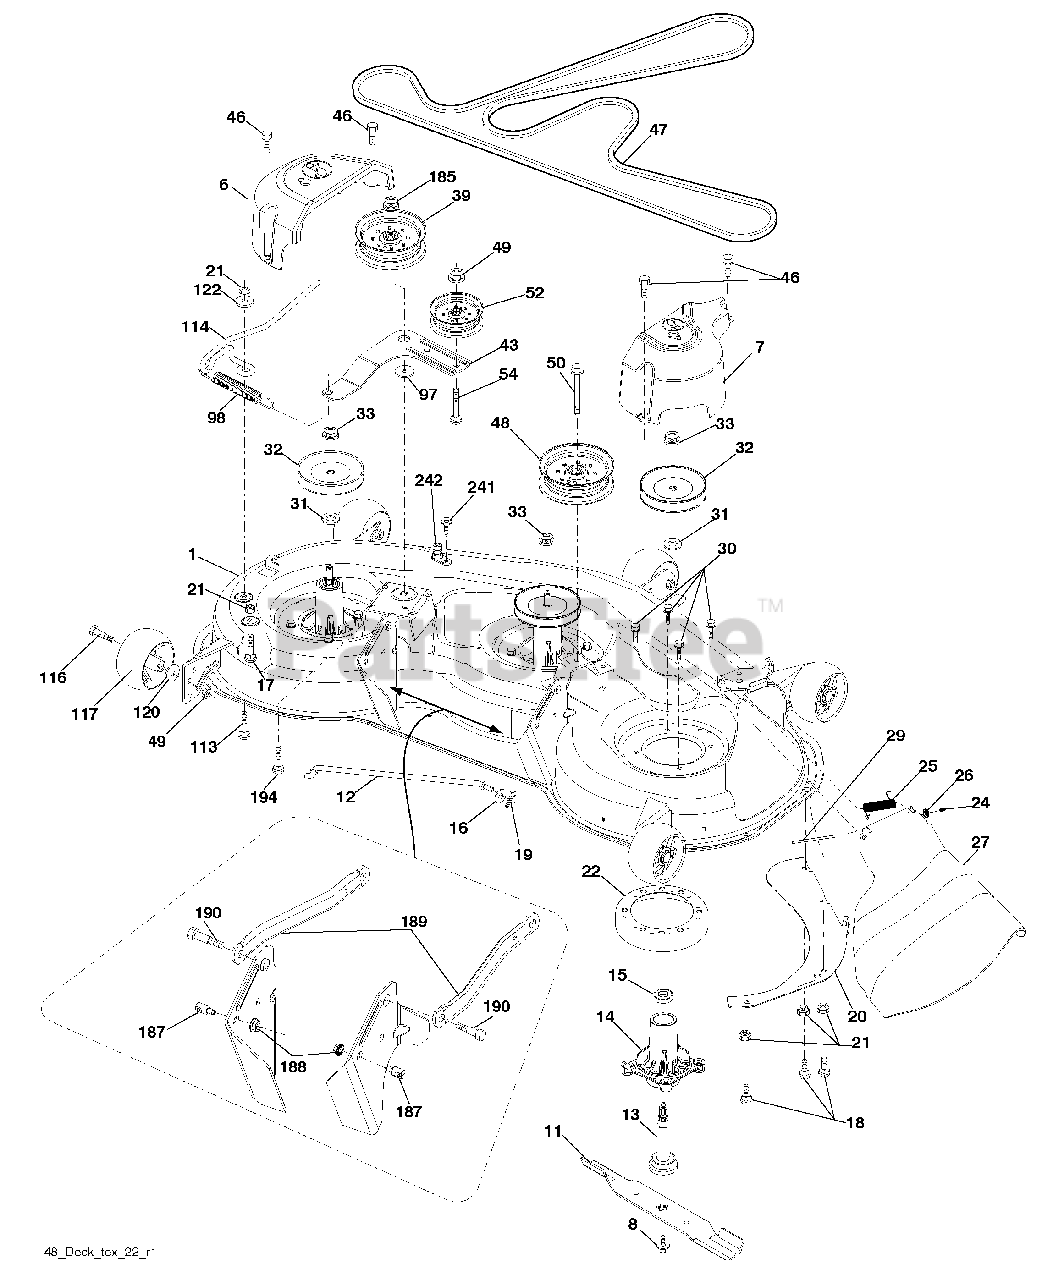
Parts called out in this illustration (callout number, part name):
1	Deck Weldment Mower
6	Cover Mandrel LH
7	Cover Mandrel RH
8	Bolt 7/16 Asm. Blade
11	Blade High Lift
12	Rod Anti-Sway
13	Shaft Asm. w/Lower Bearing
14	Housing, Mandrel
15	Bearing, Ball, Mandrel
16	Washer 13/32 x 13/16 x 12 Ga.
17	Bolt 5/16-18 x 5/8
18	Bolt RdHd 5/16-18 unc x 5/8
19	Pin Cotter 5/16 Bow Tie Lock
20	Baffle Vortex
21	Nut, Crownlock 5/16-18 unc
22	Stripper Mandrel
24	Cap Sleeve
25	Spring, Torsion
27	Deflector Shield
29	Rod, Hinge
30	Screw, Thdroll Washer Head
31	Washer, Spacer Mower Vented
32	Pulley, Mandrel
33	Nut, Flg. Top Lock
39	Pulley, Idler, 4.50 Hub
43	Arm, Idler
46	Screw, Thdroll. 1/4-20 x 5/8
47	Belt Deck Drive
48	Pulley Idler 4.50 RAW
49	Nut, Lock Flg. 3/8-16 unc
50	Screw TT 3/8-16 x 2-1/4
52	Pulley Idler 48" Primary
54	Bolt Carr. Sh 3/8-16 x 1-1/2 Gr. 5
97	Washer Hardened
98	Spring Drive
113	Bolt Rdhd Sqnk 5/16-18 x 3/4
114	Rod Tension Relief
116	Bolt, Shoulder
117	Gauge Wheel
120	Washer 13/32 x 1-1/4 x 12 Ga.
122	Bushing Tension Relief
185	Nut Lock Flange 7/16-14 Gr. 5
187	Stud Fastener w/"D" Anti-Rotation
188	Nut Lock Hex Flange
189	Arm Susp. Mower Rear
190	Bolt Shoulder
194	Bolt Carr Sqnk 7/16-24 x 2
241	Screw TT #10-32.5 3/8 Flange
242	Port, Washout
